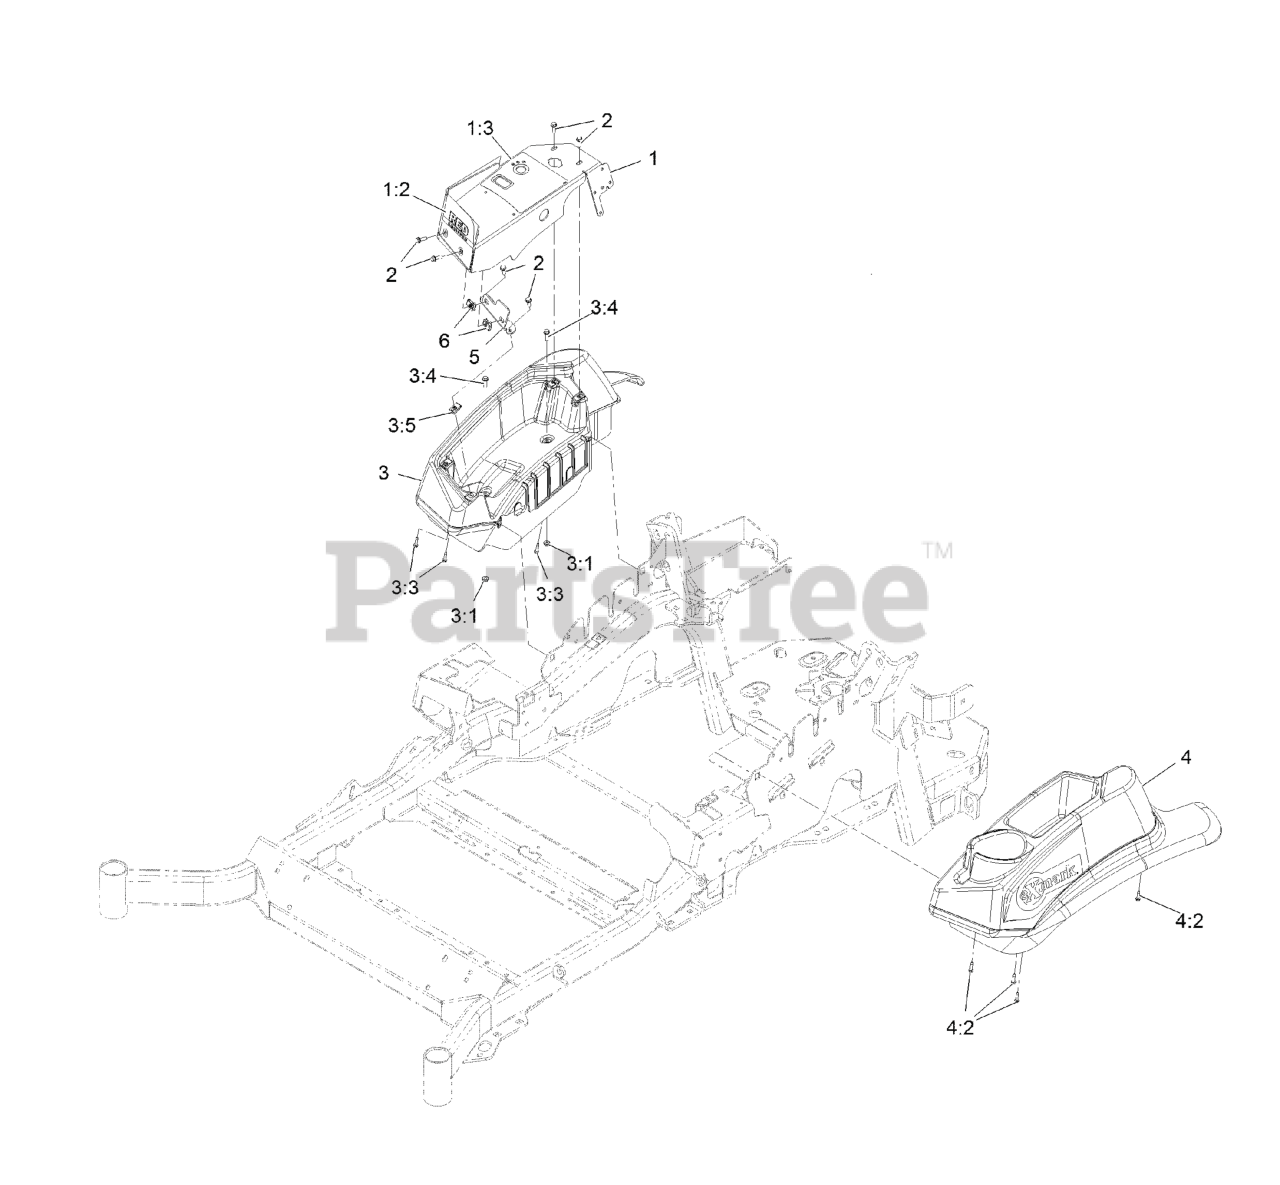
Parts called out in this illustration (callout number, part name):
1	COVER PANEL ASM W/DECALS
1:2	DECAL-CONTROL PANEL RED
1:3	DECAL-CONSOLE
2	SCREW-HWH
3	CONSOLE,RH NARROW ASM
3:3	SCREW,THD FORM,HWH
3:4	SCREW-HWH
4	CONSOLE.LH NARROW ASM
4:2	SCREW,THD FORM,HWH
5	BRACKET-CONSOLE
